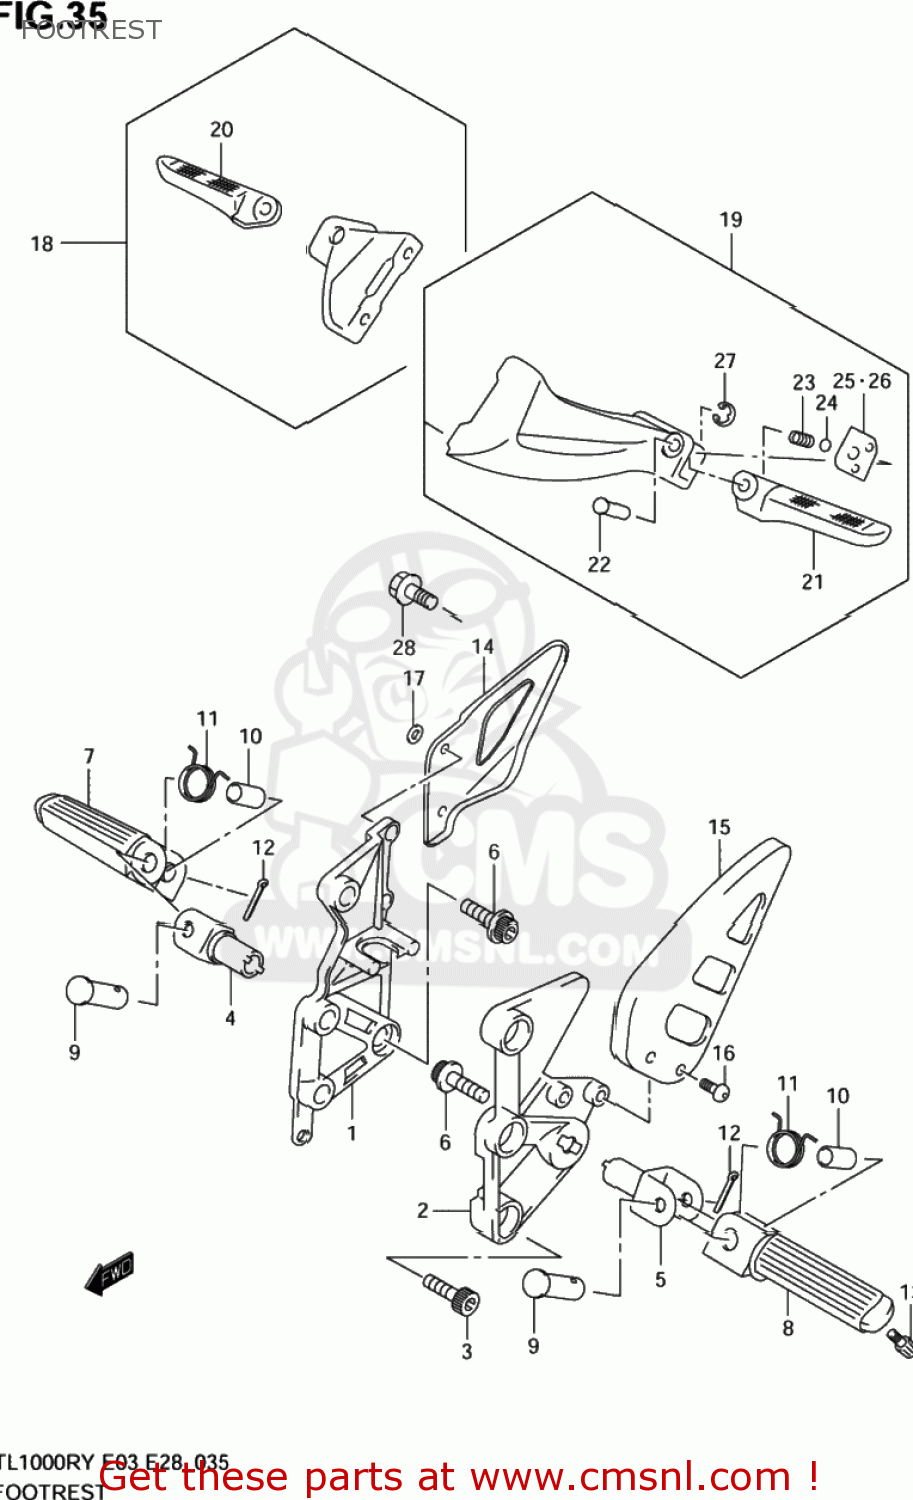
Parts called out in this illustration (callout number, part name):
1	BRACKET,FR FOOTREST,R
2	BRACKET,FR FOOTREST,L
3	BOLT
4	HOLDER,FOOTREST,R
5	HOLDER,FOOTREST,L
6	BOLT(10X28)
7	BAR,FR FOOTREST,R
8	BAR,FR FOOTREST,L
9	PIN
10	SPACER(8.1X12X22)
11	SPRING
12	PIN 20X15
13	BOLT,BANK SENSOR
14	GUARD,FR FOOTREST,R
15	GUARD,FR FOOTREST,L
16	SCREW(5X10)
17	WASHER(6.5X16X1)
18	FOOTREST ASSY,PILLION,R
19	FOOTREST ASSY,PILLION,L
20	BAR,PILLION FOOTREST,R
21	BAR,PILLION FOOTREST,L
22	PIN
23	SPRING
24	BALL
25	PLATE,PILLION,RIGHT
26	PLATE,PILLION,LEFT
27	E-RING
28	BOLT
29	BOLT
